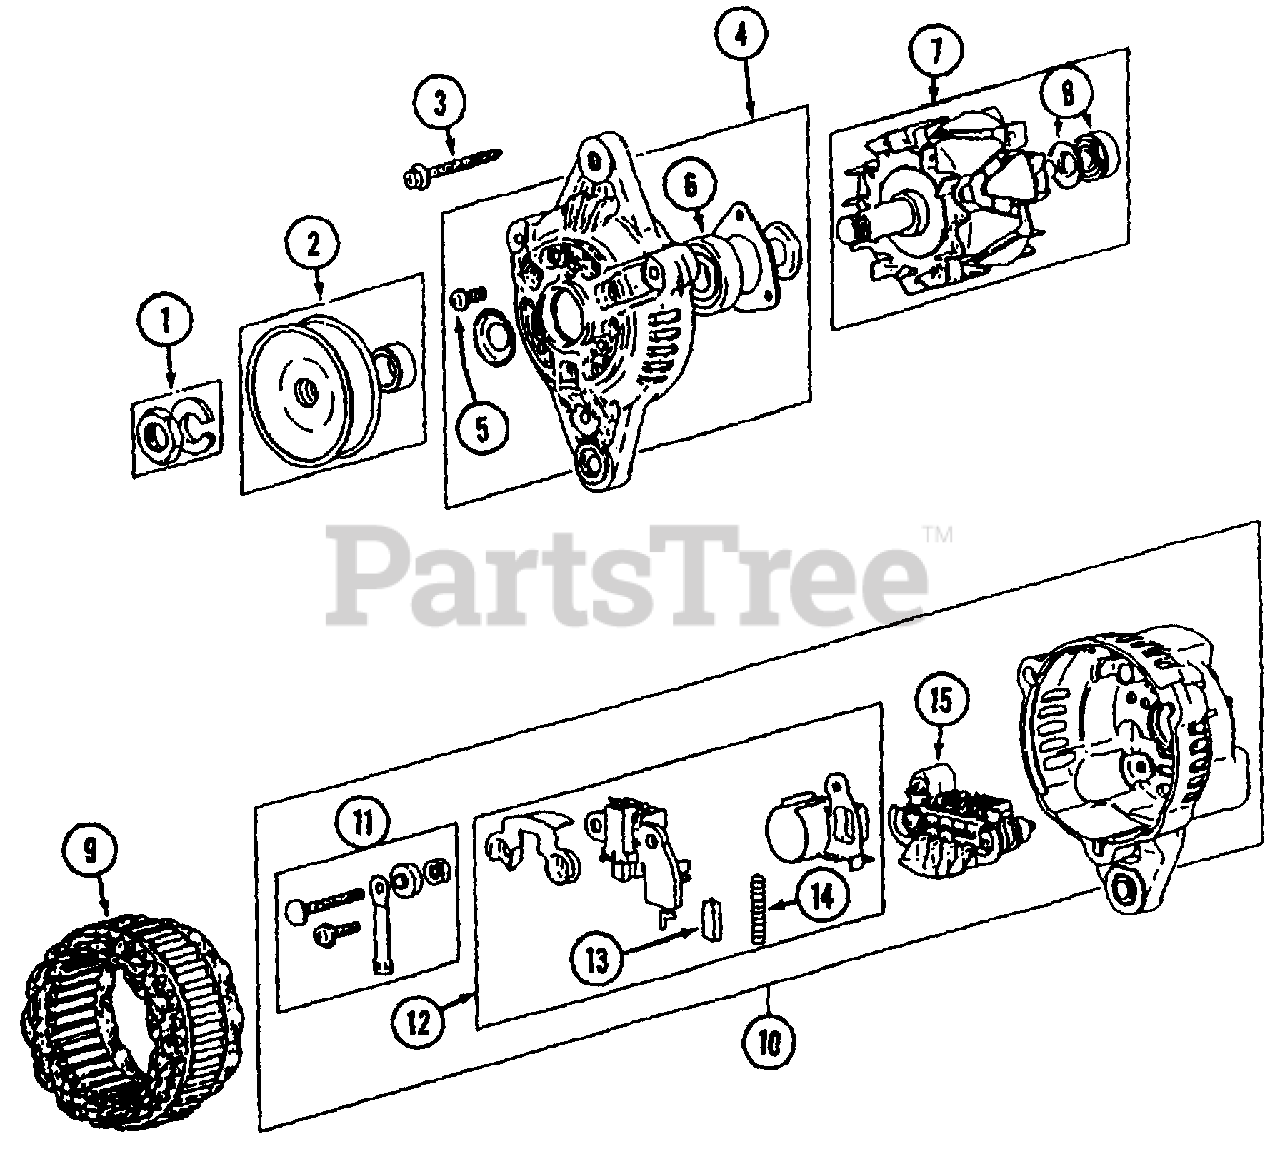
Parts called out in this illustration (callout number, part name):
4	Bracket Ass'y., Front
6	Bearing, Front
8	Bearing, Rear
9	Starter Ass'y.
10	Bracket Ass'y., Rear
12	Regulator Ass'y.
13	Brush
14	Spring, Brush
15	Rectifier Ass'y.
